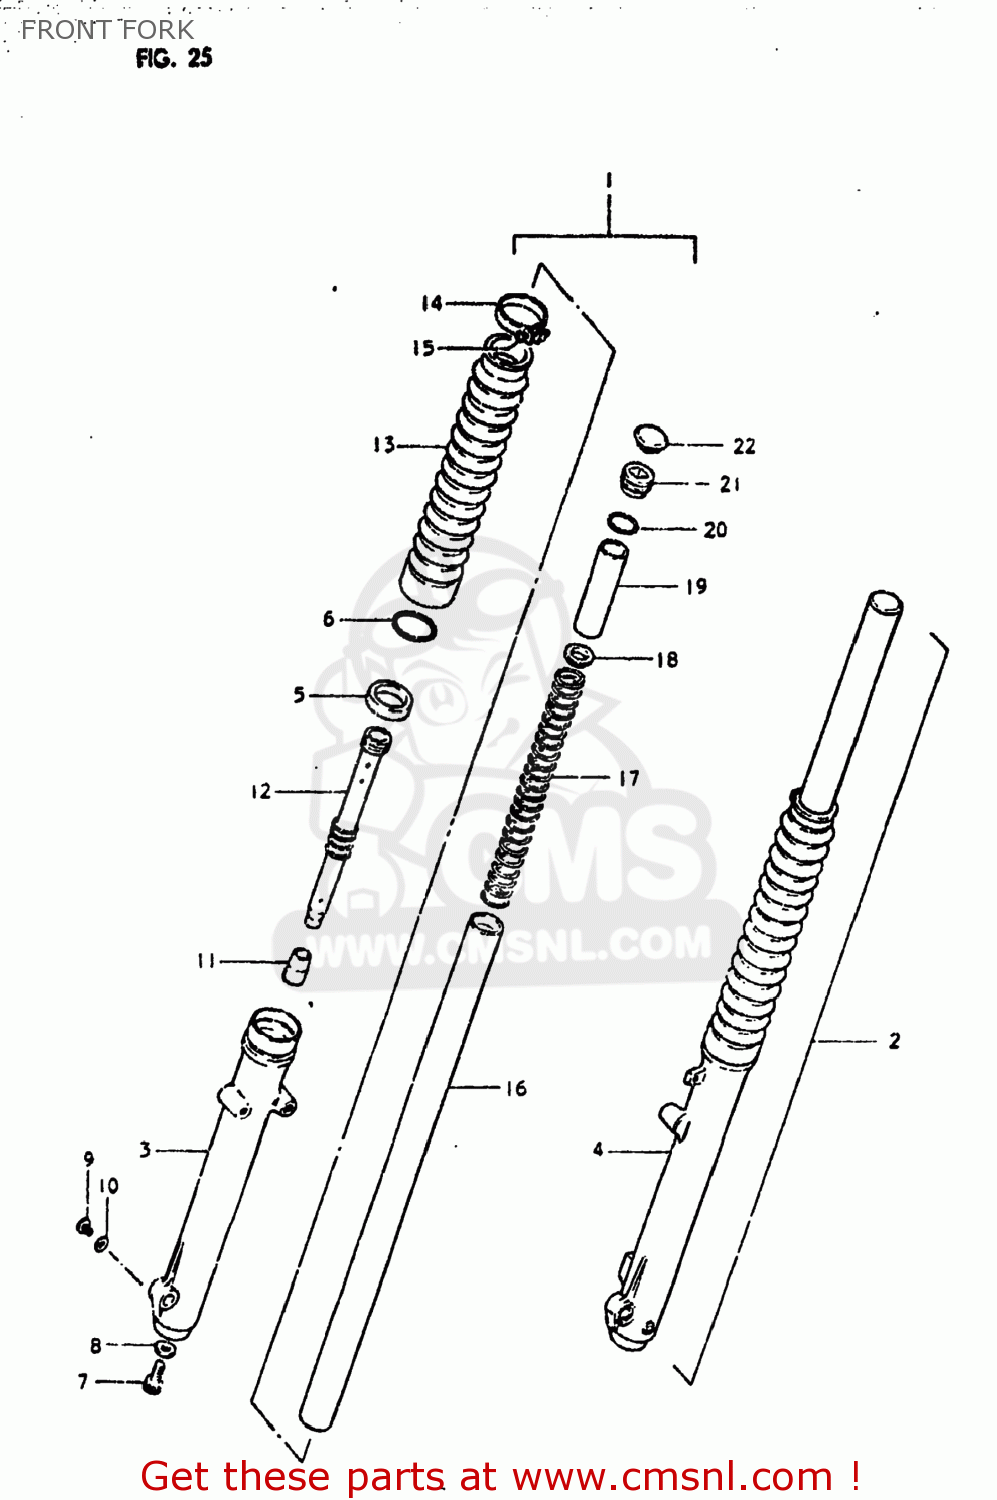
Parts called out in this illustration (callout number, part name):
1	DAMPER ASSEMBLY,RIGHT
2	DAMPER ASSEMBLY,LEFT
3	TUBE,OUTER,RIGHT
4	TUBE,OUTER,LEFT
5	OIL SEAL,FRONT FORK
6	7
7	BOLT,FORK CYLINDER(10X25)
8	GASKET (NAS)
9	SCREW
10	GASKET,DRAIN,PLUG (NAS)
11	PIECE,OIL LOCK
12	CYLINDER,FRONT FORK
13	BOOT,FRONT FORK COVER
14	BAND,BOOT
15	SCREW
16	TUBE,FORK,INNER
17	SPRING,FRONT FORK
18	GUIDE,FRONT FORK SPRING C
19	SPACER,SPRING
20	O RING
21	CAP,FORK INNER TUBE
22	CAP,FRONT FORK
